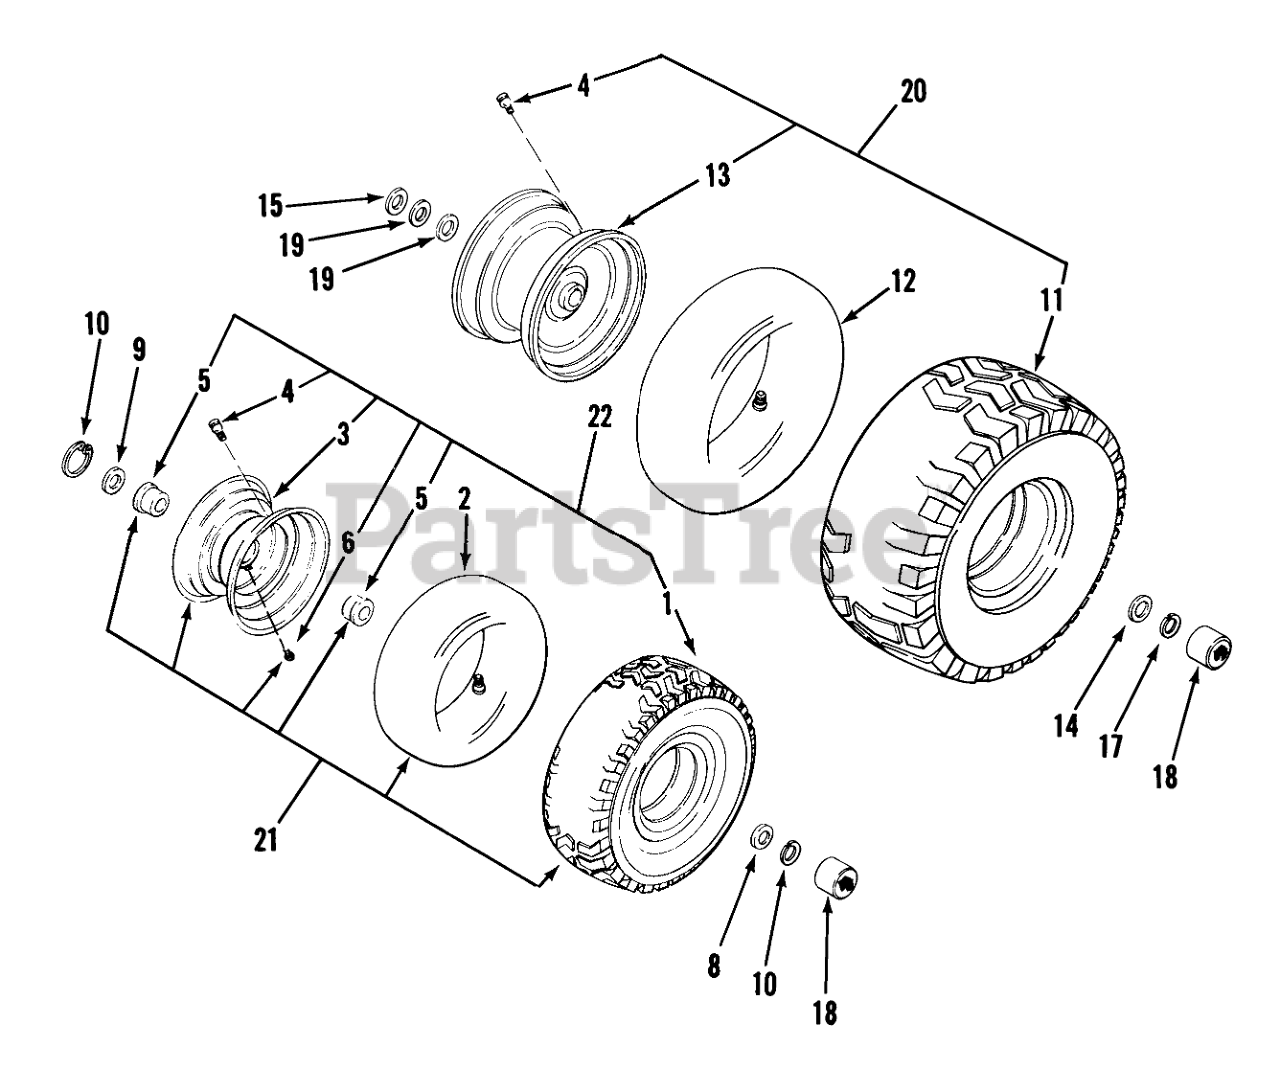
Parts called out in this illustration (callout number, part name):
1	TIRE
4	VALVE
5	BUSHING-FLANGED
8	WASHER-FLAT
9	WASHER-SHIM
9	WASHER
11	TIRE
14	WASHER-FLAT
15	WASHER
19	WASHER-SHIM
22	ORDER COMPONENT PARTS
